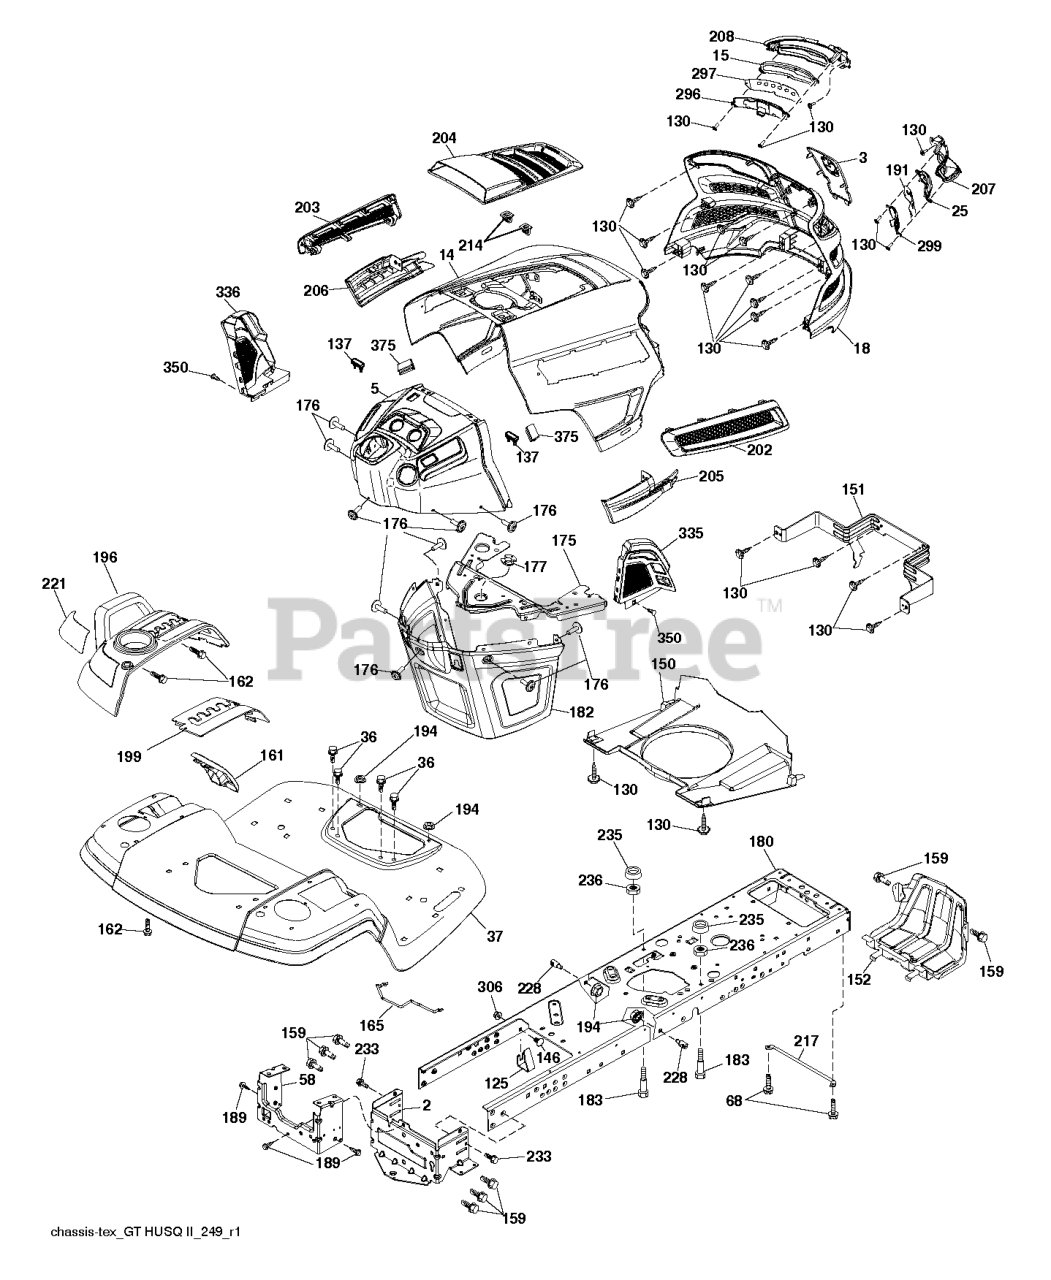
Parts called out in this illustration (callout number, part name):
2	DRAWBAR.LOWER.2PC.18/22
3	APPLIQUE.SUBASM.GT.HUSQ.II
5	DASH.UPP.GT2.DUAL.RD.PTO.MCHOK
14	HOOD.ASM.HUSQVARNA.GT.TEX.ORAN
15	LED LIGHT.LH
18	GRILLE SUBASM.GT.II.LOW.HDLGHT
25	LENS.RH
36	SCREW 5/16"
37	FENDER.PNT.TX.GT.CH/FW/DL.HUSQ
58	DRAWBAR.UPPER.2PC,LRG.FENDER
68	SCR 5/16-18 X 1/2 SELFTAP ZN
125	CLIP.FUEL.LINE
130	SCREW.#10 X 0.750.BOS
137	BUMPER DASH
146	BOLT.RDHD.SHT.SQNK.3/8-16X5/8
150	AIR.DUCT.GTV.BLACK
151	BRACKET.PIVOT.HOOD.GT.HUSQ.II
152	SHIELD.BROWNING.PNT.GT.V2
159	SCREW, 3/8-16X3/4
161	CONSOLE.WINDOW.FUEL.HUSQ.GT
162	SCREW.HI-LO.CONSOLE
165	SUPPORT.TANK.REAR.B/TE
175	PLATE.PNT.CROSSMEMBER.HUSQ/PRE
176	SCREW.#10-24X5/8.RN.QU
177	BUSHING STEERING
180	CHASSIS.LT/GT.BOLTED
182	DASH.LOWER.COMMON.12V.ADAPTOR
183	BOLT.5/16-18X1-1/4 FULL THD
189	SCREW
191	INSERT INFLECT.RH
194	NUT LOCK HEX FLANGE 5/16-18
196	CONSOLE.ASM.DECKLIFT.HUSQGT.DL
199	PLATE.DECK.LIFT.HUSQVARNA.GT
202	VENT.SIDE.RH.GT.HUSQ.II.
203	VENT.SIDE.LH.GT.HUSQ.II.498
204	VENT.TOP.HUSQ.GT2
205	SIDE.TRIM.RH.GT.HUSQ.II
206	SIDE.TRIM.LH.GT.HUSQ.II.GRAY
207	BEZEL GT2 LED RH W/ LOWER.ATT
208	BEZEL GT2 LED LH W/ LOWER ATT
214	CLIP.RETAINER.TINNER.
217	ROD.PIVOT.HOOD
221	REFLECTOR.LH.TEX GT HU
228	STUD.FASTNER.W/ANTI-ROTATE
233	BOLT.SHOULDER
235	SPACER FENDER
236	NUT.CENTERLOCK.5/16-
296	LED LIGHT.LH
297	INSERT REFECT LH
299	LED LIGHT.RH
306	NUT LOCK FLG 3/8-16 UNC
335	COVER.LOWER.DASH.RH.BLACK
336	COVER-LH.LOWER.DASH.GT2.BLACK
350	CLIP.X-MAS.TREE
375	BUMPER CLIP-ON. DASH 1"
